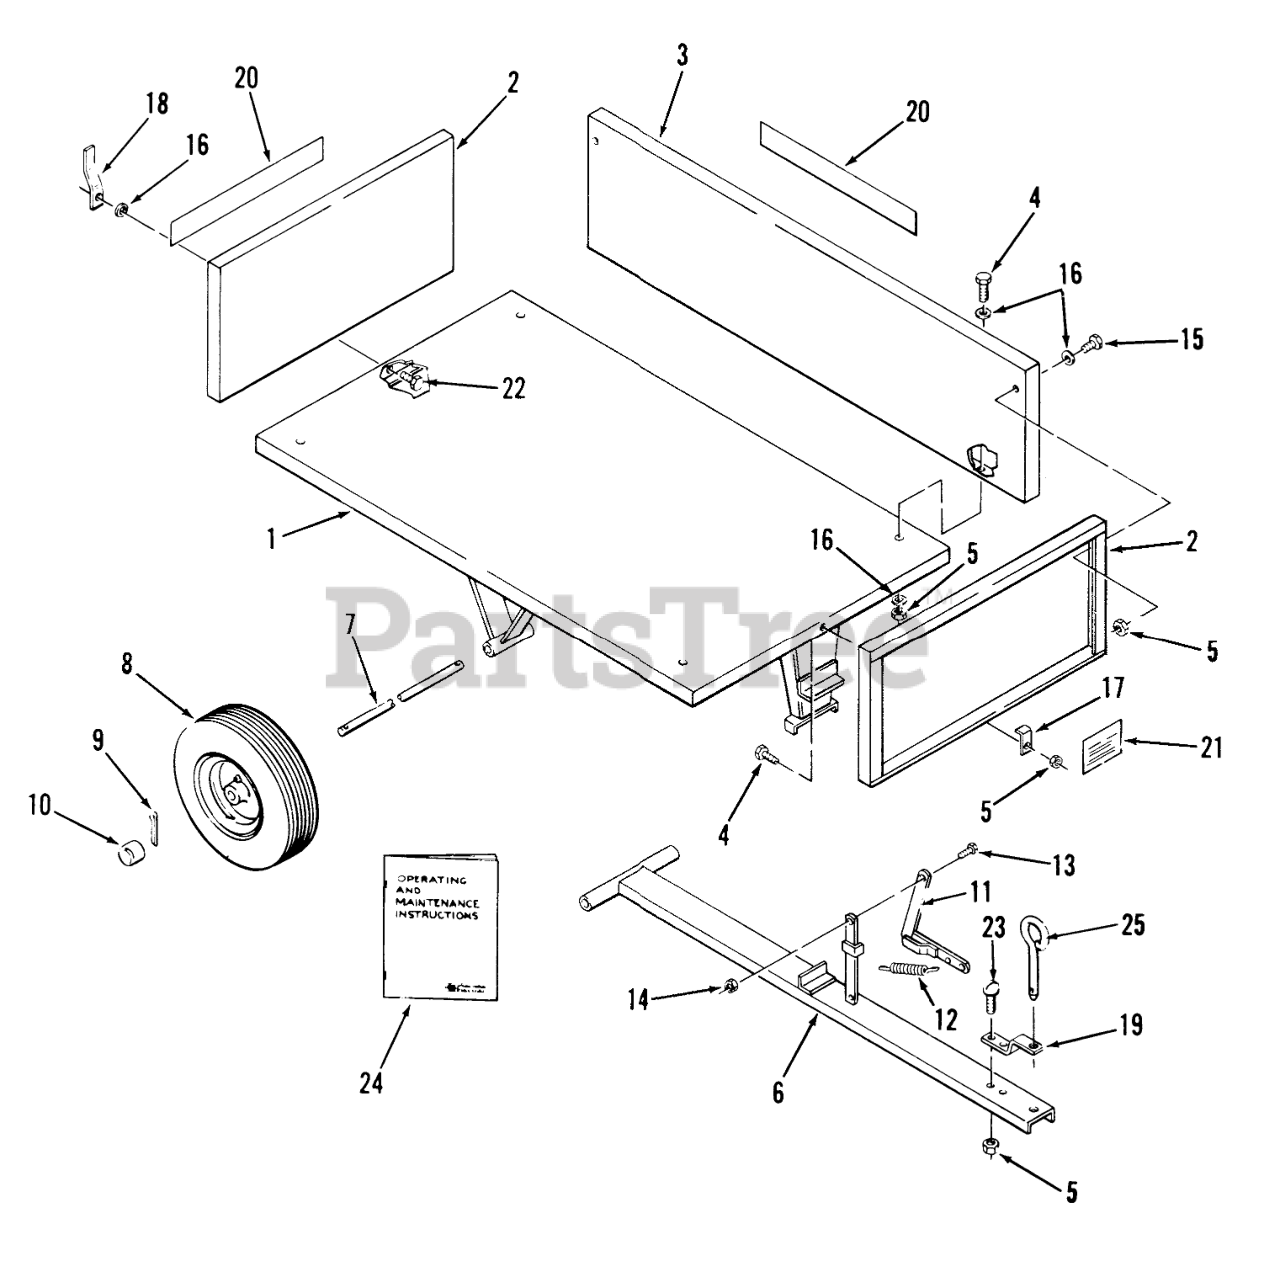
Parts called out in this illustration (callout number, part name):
1	Bed Assembly
2	Front and Rear Gate
3	Side Gate
4	BOLT
5	NUT
6	Drawbar Assembly
8	Wheel Assembly (6.50 x 8-16)
9	Cotter Pin
10	HUB CAP
11	Latch Assembly
12	SPRING
13	Bolt
14	Nut
15	Bolt
16	Washer
17	Latch-Front Gate
18	Latch-Rear Gate
19	CLEVIS-BAR
20	Decal
21	Weight Limit Decal
22	Bolt
23	Truss Hd. Bolt 3/8-16 x 3/4
24	Operating and Maintenance Instructions
25	PIN-TOOL
